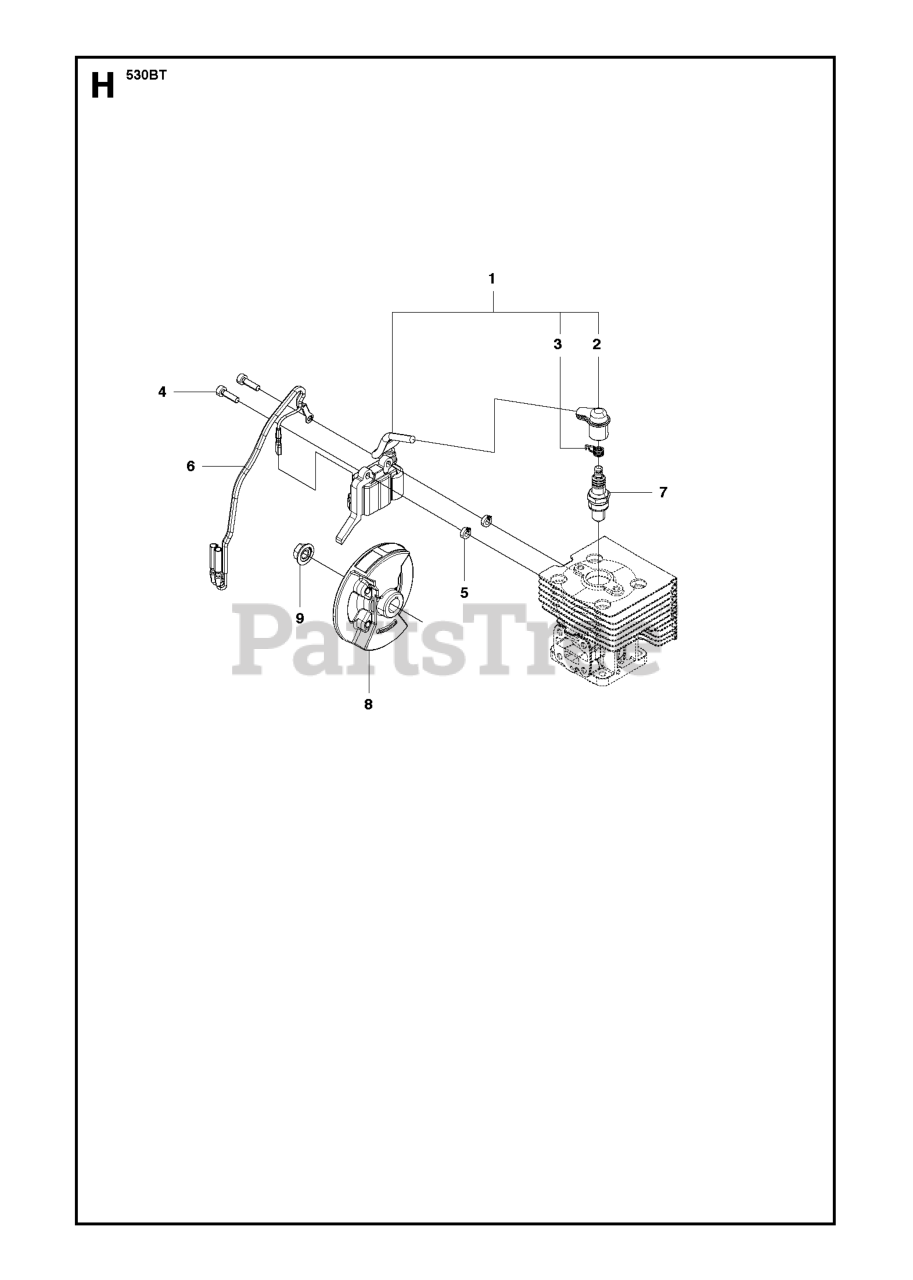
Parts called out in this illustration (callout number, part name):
2	HUB CAP 848F6L71E0
3	SPRING
7	SPARKPLUG NGK CMR7H
9	NUT
